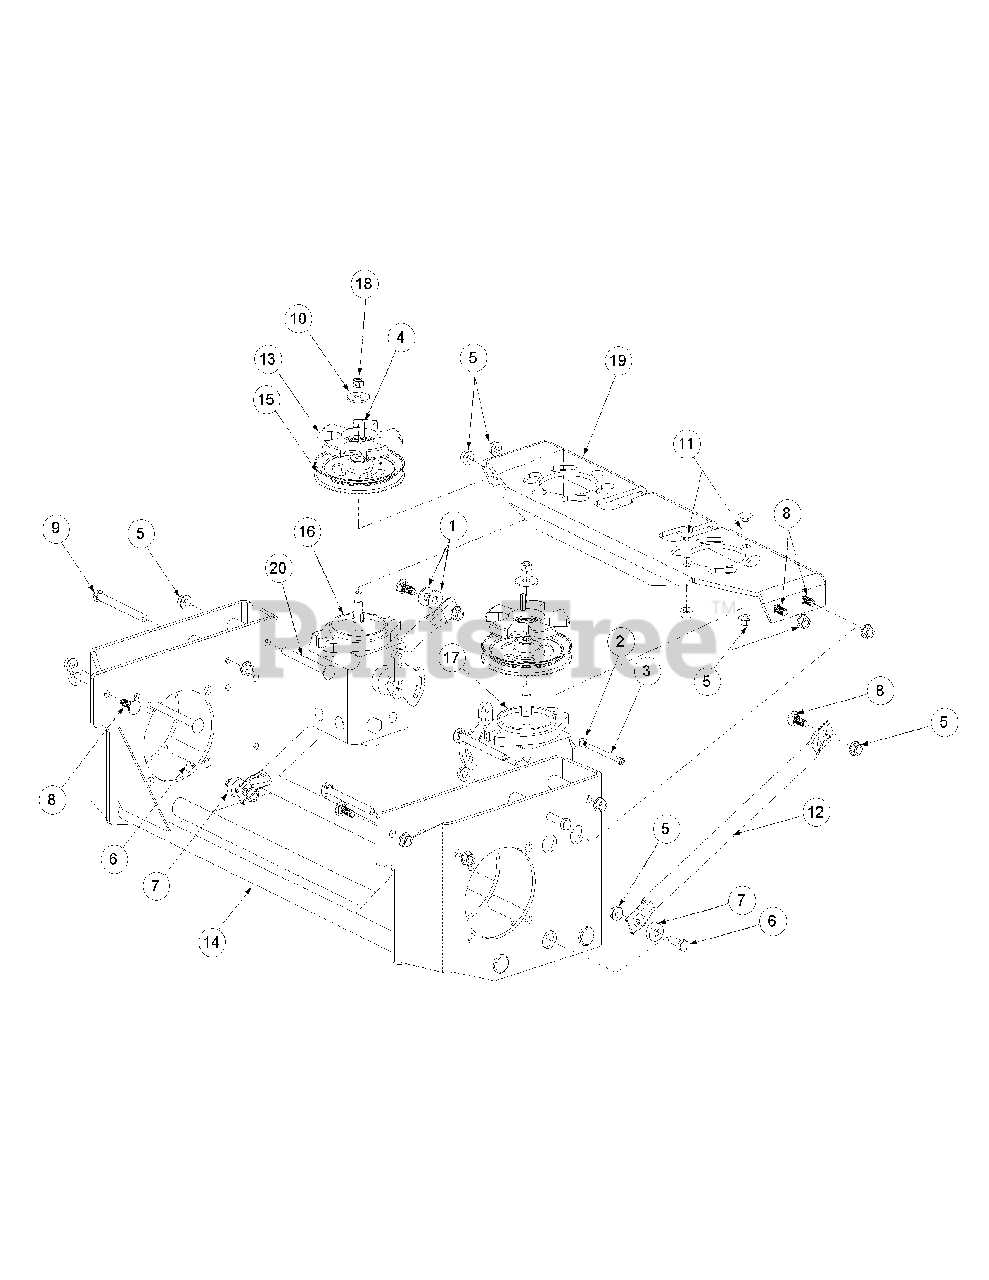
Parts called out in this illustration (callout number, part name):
1	Lock Washer, 3/8
2	Lock Nut, Nylon Insert, 1/4-20
3	Socket Head Cap Screw, 1/4-20 x 2-1/2
4	Key, 3/16" x 7/8"
5	Flange Lock Hex Nut, 3/8-16
6	Hex Cap Screw, 2/8 -16 x 1.25
7	Spacer, .406 ID x 1.00 OD x .38
8	Carriage Bolt, 3/8-16 x 1
9	Hex Cap Screw, 3/8-16 x 4.00
10	Flat Washer, .411 x 1.25 x .100
11	Carriage Screw, 3/8-16 x 1.25
13	Hydro Pulley Fan
14	Hydro Motor Frame Assembly
15	Hydro Pulley Pump
16	Hydro Pump, LH
17	Hydro Pump, RH
18	Hex Nut, 3/8-24
19	Hydro Pump Mounting Weldment
20	Carriage Bolt, 3/8-16 x 4"
